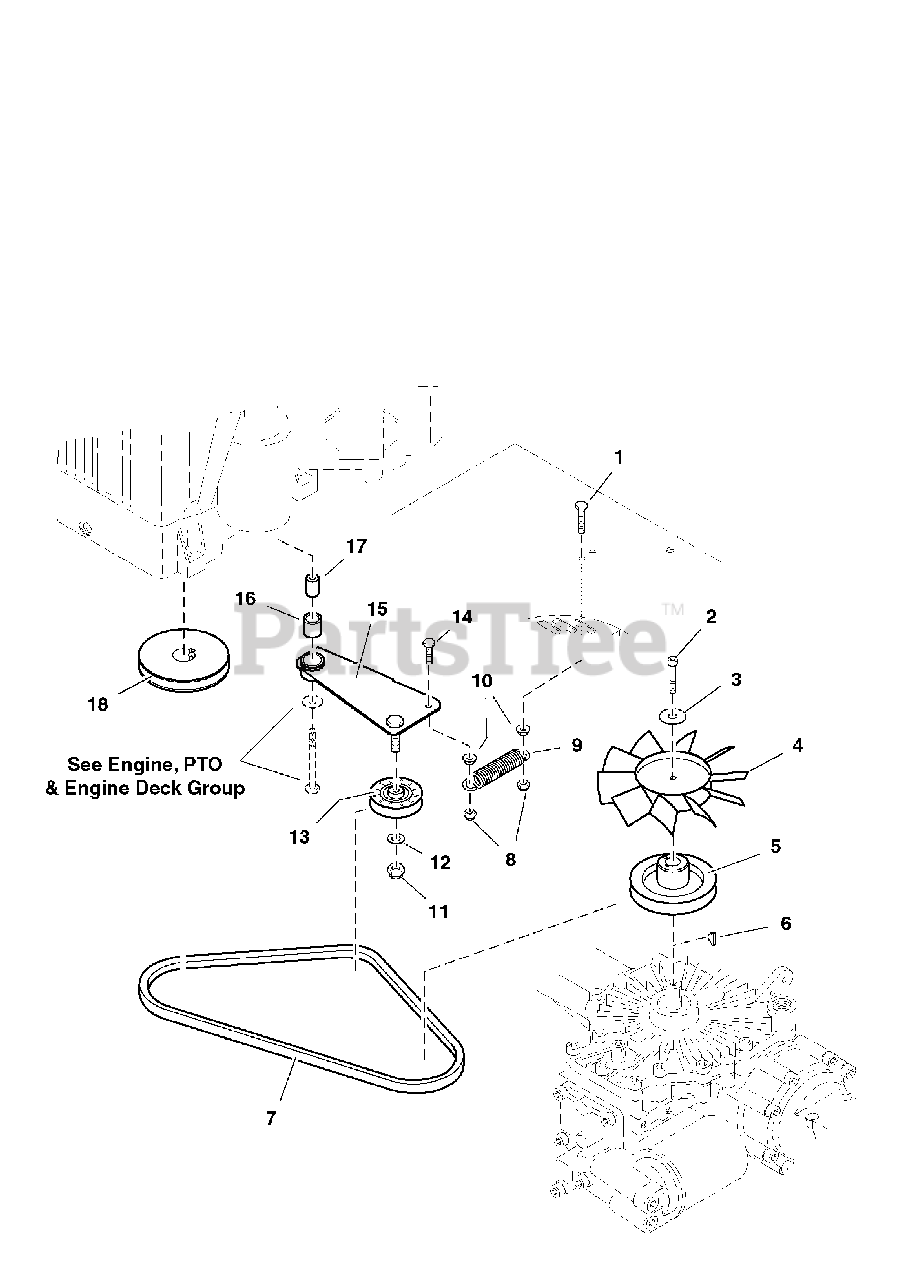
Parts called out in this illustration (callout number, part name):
1	CAPSCREW, Hex Hd, TFL, 5/16-18 x 1-3/4
2	CAPSCREW, Allen Hd, 1/4-20 x 1-3/4
3	WASHER, .265 x 1.50 x .109
5	PULLEY, Transaxle Drive
6	KEY, Hi-Pro Woodruff
8	NUT, Hex, Nylon Lock, 5/16-18
9	SPRING, Extension
10	NUT, Hex, Serrated Flange, 5/16-18
11	NUT, Hex, Nylon Lock, 3/8-16
12	WASHER, 3/8
13	PULLEY, Idler
14	CAPSCREW, Hex Hd, TFL, 5/16-18 x 1-1/4
15	IDLER ARM ASSEMBLY, complete (includes Ref 16)
16	BUSHING, Brass
17	PIVOT SPACER
18	PULLEY, Crankshaft
